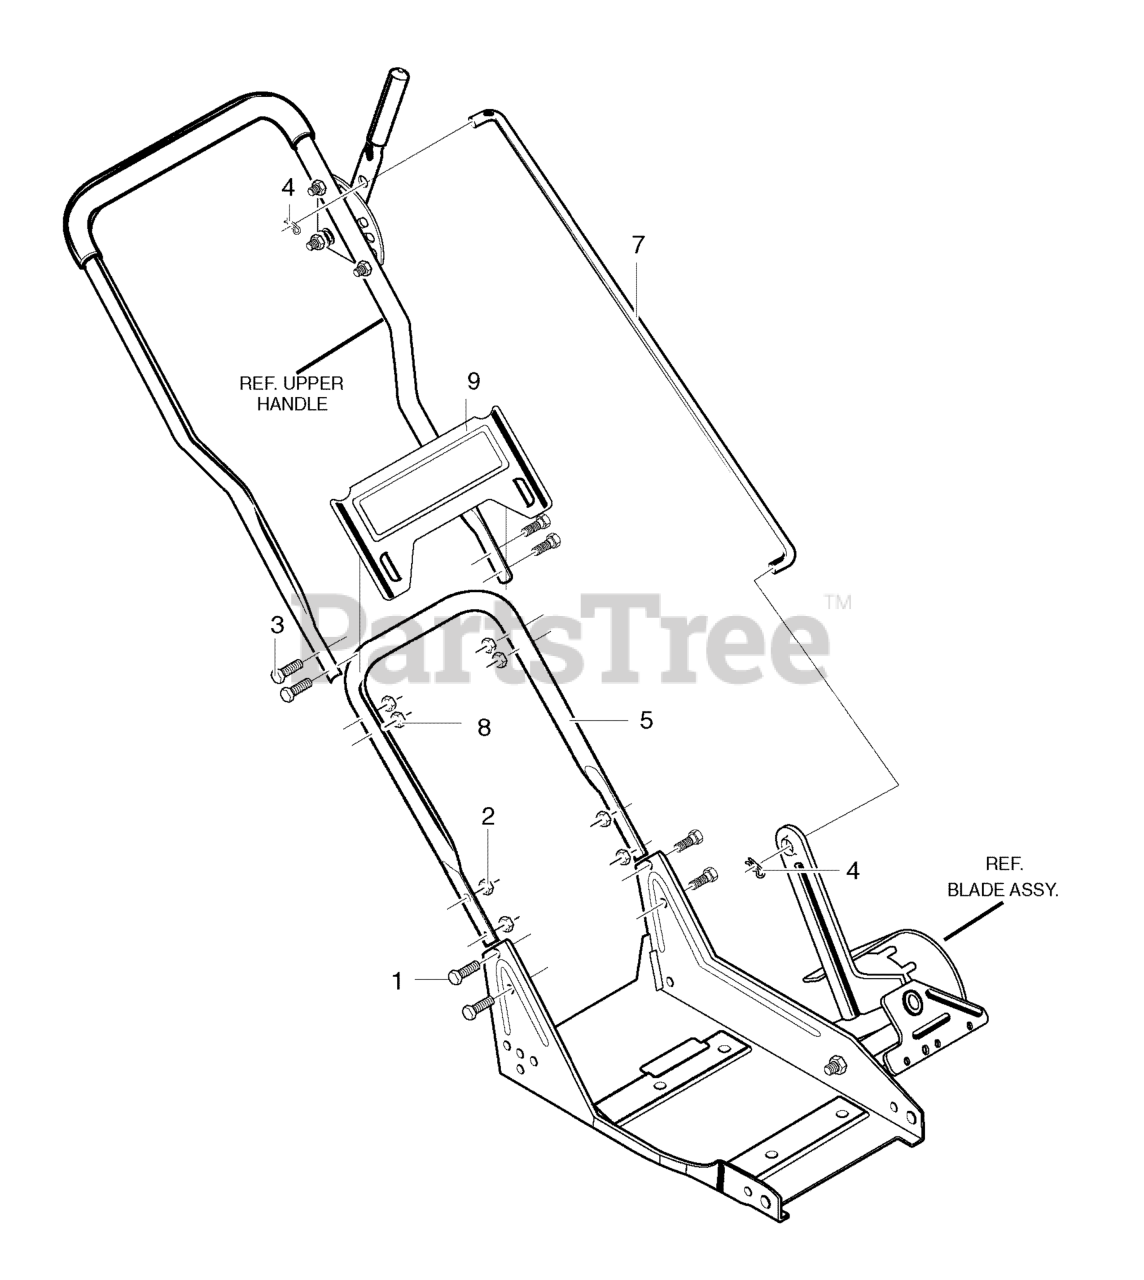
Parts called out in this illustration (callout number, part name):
1	SCREW, 5/16-18 x 0.63
2	NUT, 5/16-18
3	BOLT, 5/16-18x1.63
5	HANDLE, Lower
7	ROD, Control
8	NUT, 5/16-18
9	PANEL, Handle
